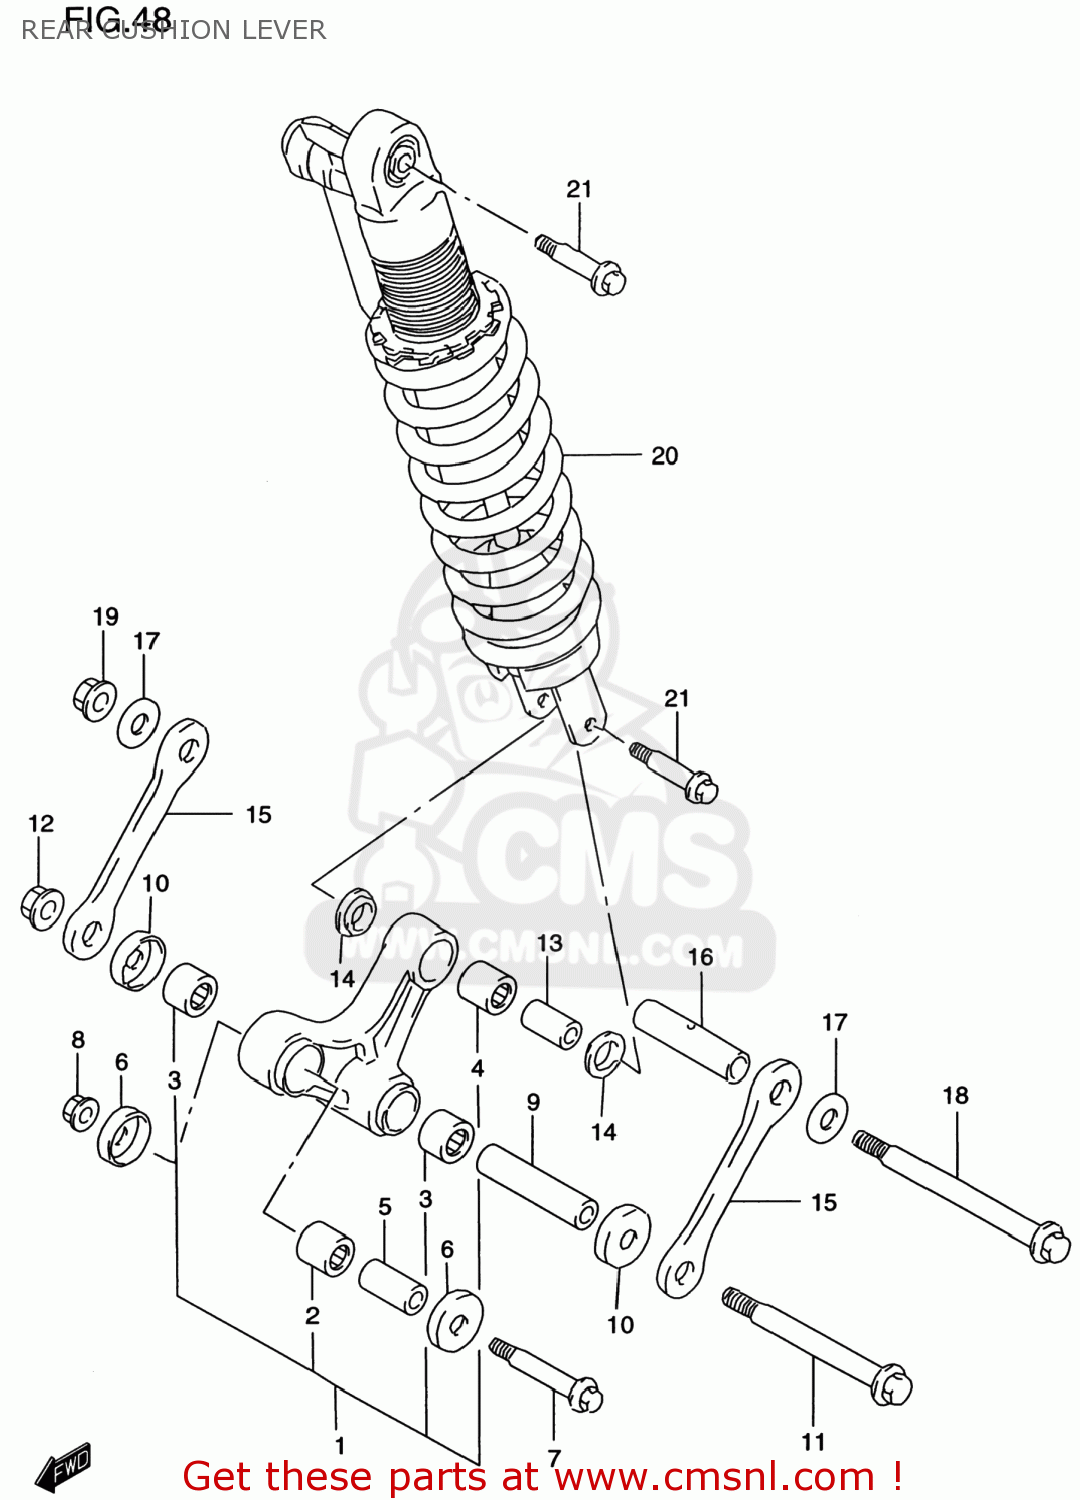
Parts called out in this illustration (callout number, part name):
1	LEVER SET,RR CUSHION
2	BEARING(20X27X30)
3	BEARING(21X27X20)
4	BEARING(17X24X20)
5	SPACER,RR CUSHION LEVER FR
6	SEAL,RR CUSHION LEVER FR DUST
7	BOLT,RR CUSHION LEVER FR
8	NUT 12MM
9	SPACER,RR CUSHION LEVER CTR
10	SEAL,RR CUSHION LEVER CTR
11	BOLT,RR CUSHION LEVER CTR
12	NUT
13	SPACER,RR CUSHION LEVER
14	SEAL,RR CUSHION LEVER RR DUST
15	ROD,RR CUSHION LEVER
16	SPACER,RR CUSHION LEVER CTR
17	WASHER
18	SHAFT,RR CUSHION LEVER FR
19	NUT
20	ABSORBER ASSEMBLY,REAR SHOCK
21	BOLT,RR CUSHION ROD UPR
